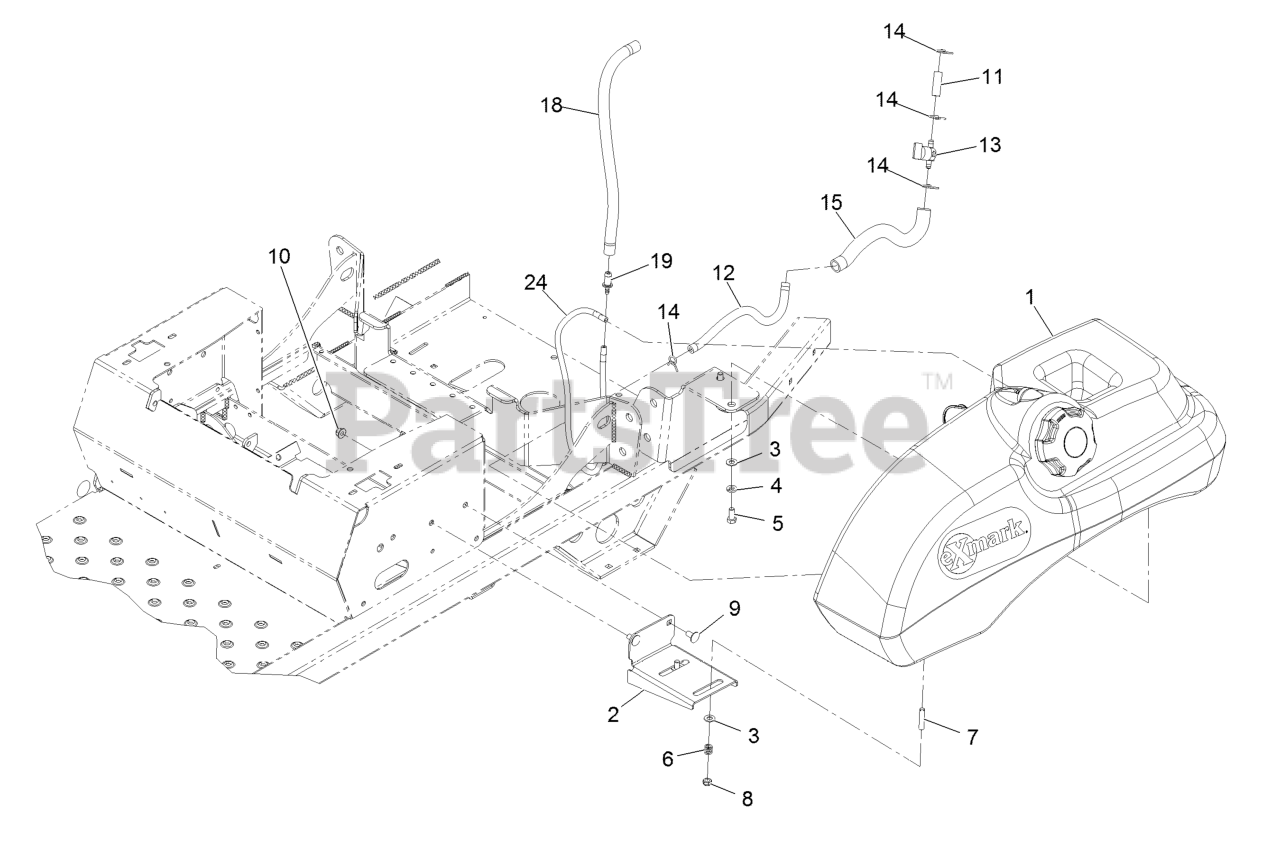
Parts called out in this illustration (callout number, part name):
1	ASM-FUEL TANK
2	BRACKET-TANK AND FENDER
3	WASHER-PLAIN
4	WASHER-LOCK
5	SCREW-HH
6	SPRING-TANK, FUEL
7	STUD
8	NUT-LOCK, NI
9	SCREW-CARR
10	NUT-HF, NI
11	HOSE-FUEL
12	HOSE-FUEL
13	VALVE-FUEL
15	CONDUIT-FUEL LINE
18	HOSE-FUEL
19	FITTING-ORIFICE, STRAIGHT
24	HOSE,EMISSIONS
